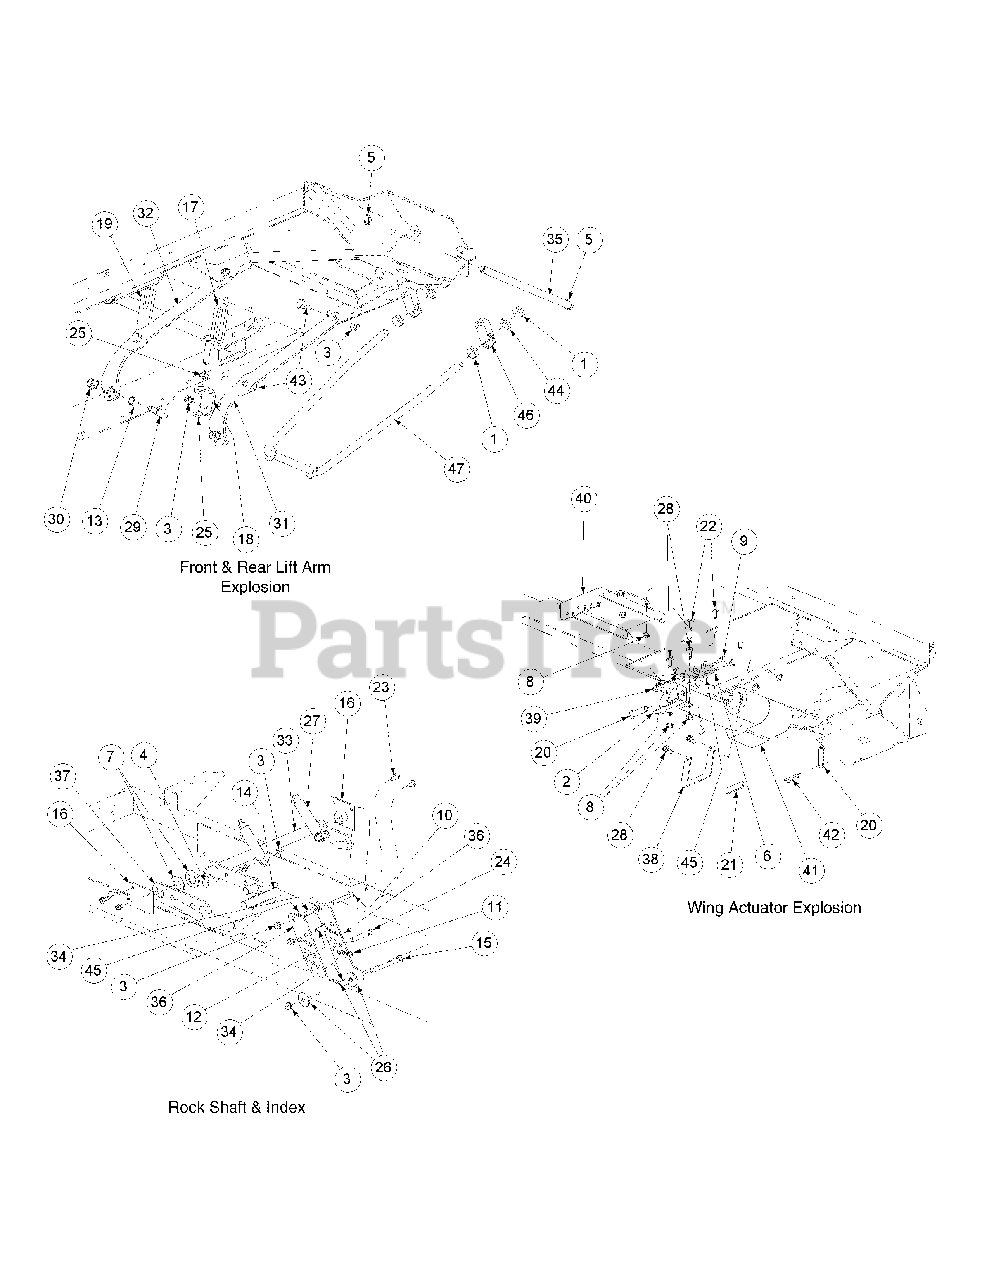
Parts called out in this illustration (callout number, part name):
1	Hex Nut, 5/8-11
2	Cable Bracket
3	Flange Lock, Hex Nut, 3/8-16
4	Carriage Bolt 3/8-16 x 1.50
5	Cotter Pin, 3/16 x 1-1
6	Spacer, Control Rod
8	Nut, Lock, HexFlange, 5/16-18
9	Shoulder Bolt, 3/8 x 3/8
10	Carriage Bolt 3/8-16 x 2.50
11	Cotter Pin, .148 x 3.00
12	Shoulder Screw, .50 OD x 0.27
13	Bearing
14	Lift Handle Grip
15	Carriage Bolt, 3/8-16 x 4.00
16	Lift Hub Assembly
17	Upper Link Lift Assembly, Left Hand
18	Lower Lift Bracket, Left Hand
19	Link Lift PLate, Right Hand
20	Clevis Pin, .500 Dia. x 1.75 Lg.
21	Battery Edge Trim
22	Carriage Bolt, 5/16-18 x .75
23	Self Tapping Screw, 5/16-18 x 3/4
24	Clevis Pin, .438 Dia. x 2.625 Lg.
25	Jam Nut, 1/2-20
26	Washer, 5/16-18
27	Extension Spring, .98 OD x 5.00
28	Hex Head Cap Screw, 5/16-18 x 0.75
29	Shoulder Screw, 0.625 x 0.75
30	Nut, 1/2-13, Flangelock
31	Rear Lift Arm, LH
32	Rear Lift Arm, RH
33	Lift Shaft Assembly
34	Spacer, .375 x .5 x 1.176 Lg.
35	Front Lift Rod
36	Lift Index Plate
37	Lift Handle Assembly
38	Actuator Bracket
39	Actuator Mounting Bracket
40	Cable Mounting Bracket Assembly
42	Hair Pin
43	Shoulder Screw, 3/8-16, .56 x .27
44	Lock Washer
45	Flat Washer, 3/8
46	Front Lift Rod Tube
47	Front Lift Rod
